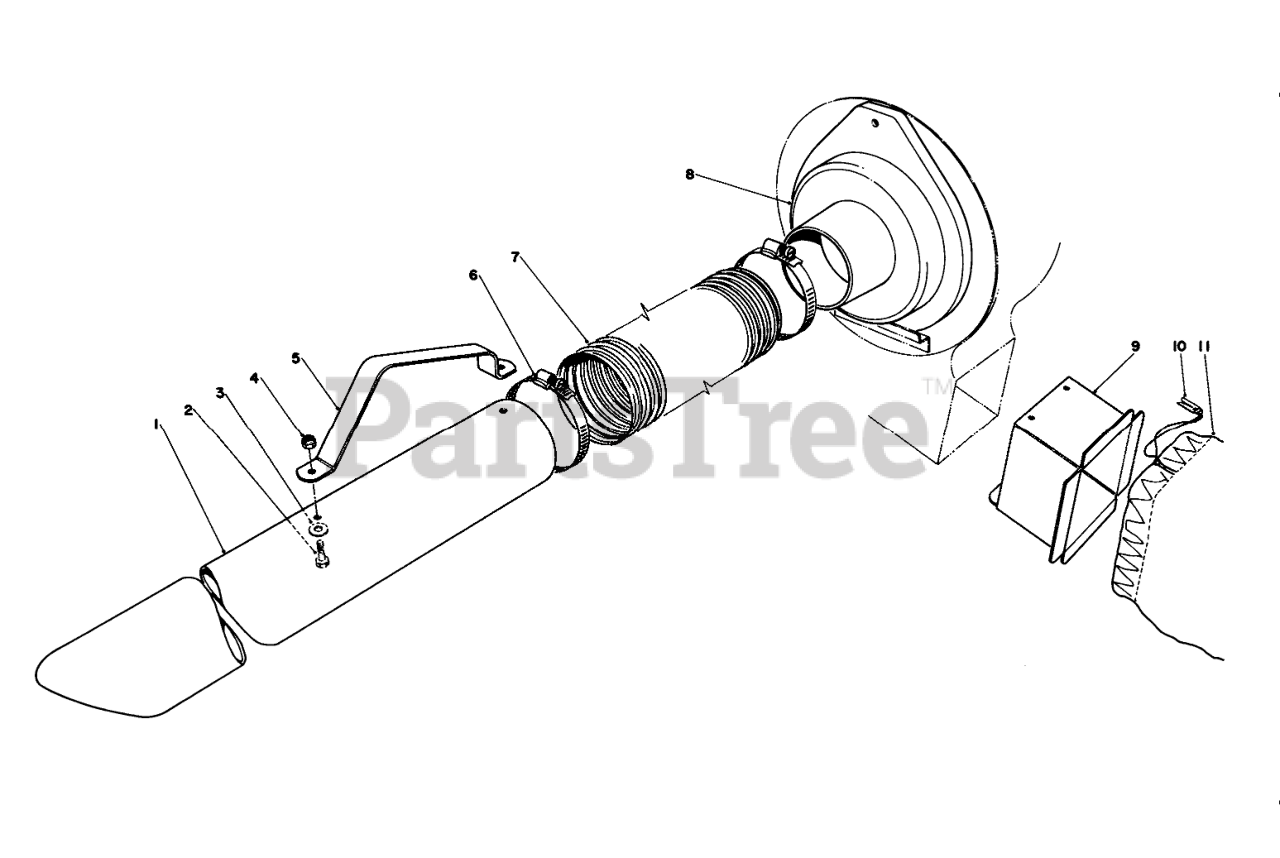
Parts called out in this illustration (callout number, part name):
1	NOZZLE
2	SCREW-HH
3	SPECIAL WASHER
4	NUT-KEPS
5	NOZZLE HANDLE
6	CLAMP
7	VACUUM HOSE
8	ADAPTOR HOSE TO HSG
9	HOUSING WA BLOWER BAG
10	BAG CORD FASTENER
11	GIANT BAG(29-9860) WW
